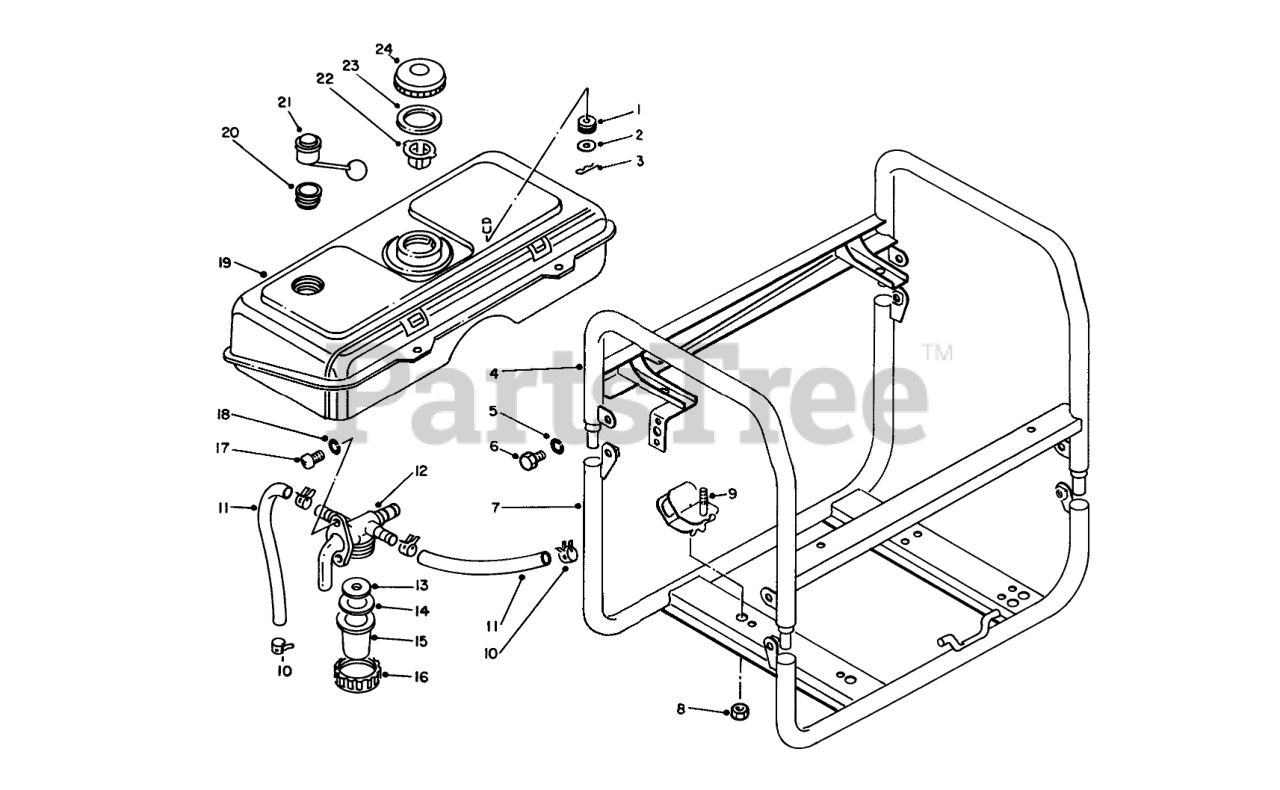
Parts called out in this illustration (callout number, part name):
1	CUSHION
2	WASHER
4	Frame-Upper
5	WASHER-LOCK
7	Screw
9	Mount-Engine
12	Cock Assembly-Fuel (Incl. Ref. #13-16)
13	FILTER
14	GASKET
17	Screw
18	Lockwasher
19	Tank-Fuel
20	Gasket
21	Gauge Assembly-Fuel (Incl. Ref. #20)
22	FILTER
23	GASKET
24	Cap (Incl. Ref. #23)
